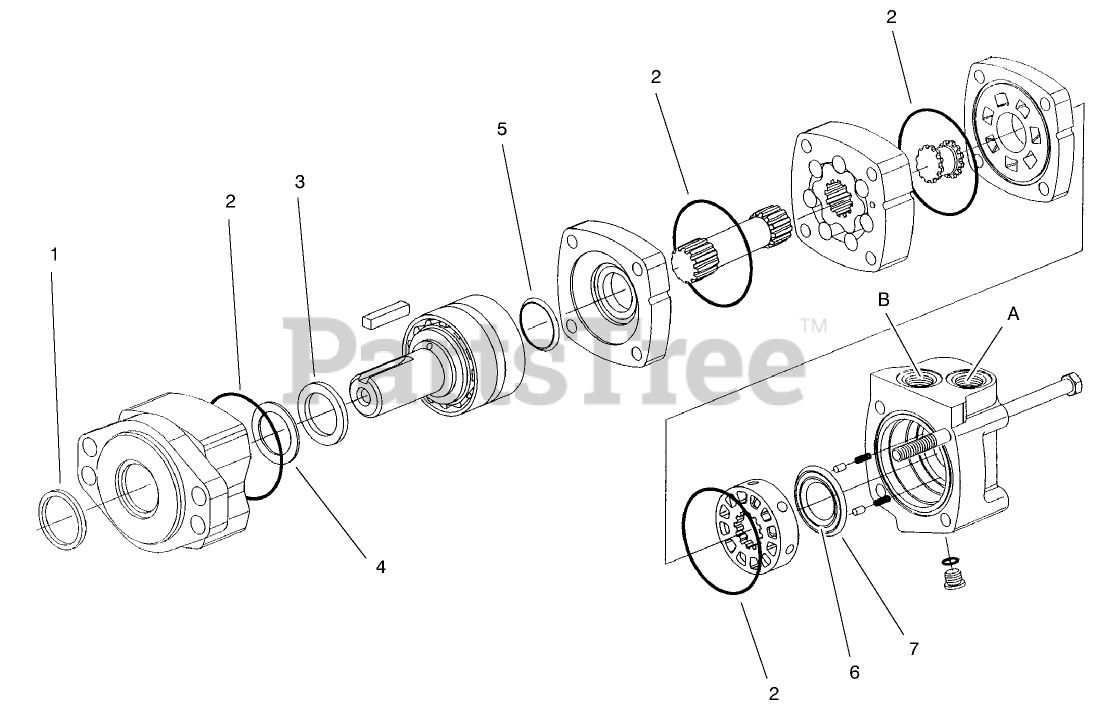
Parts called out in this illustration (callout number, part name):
2	Seal-O-Ring
4	Back-up-Washer
7	Seal-Outer
